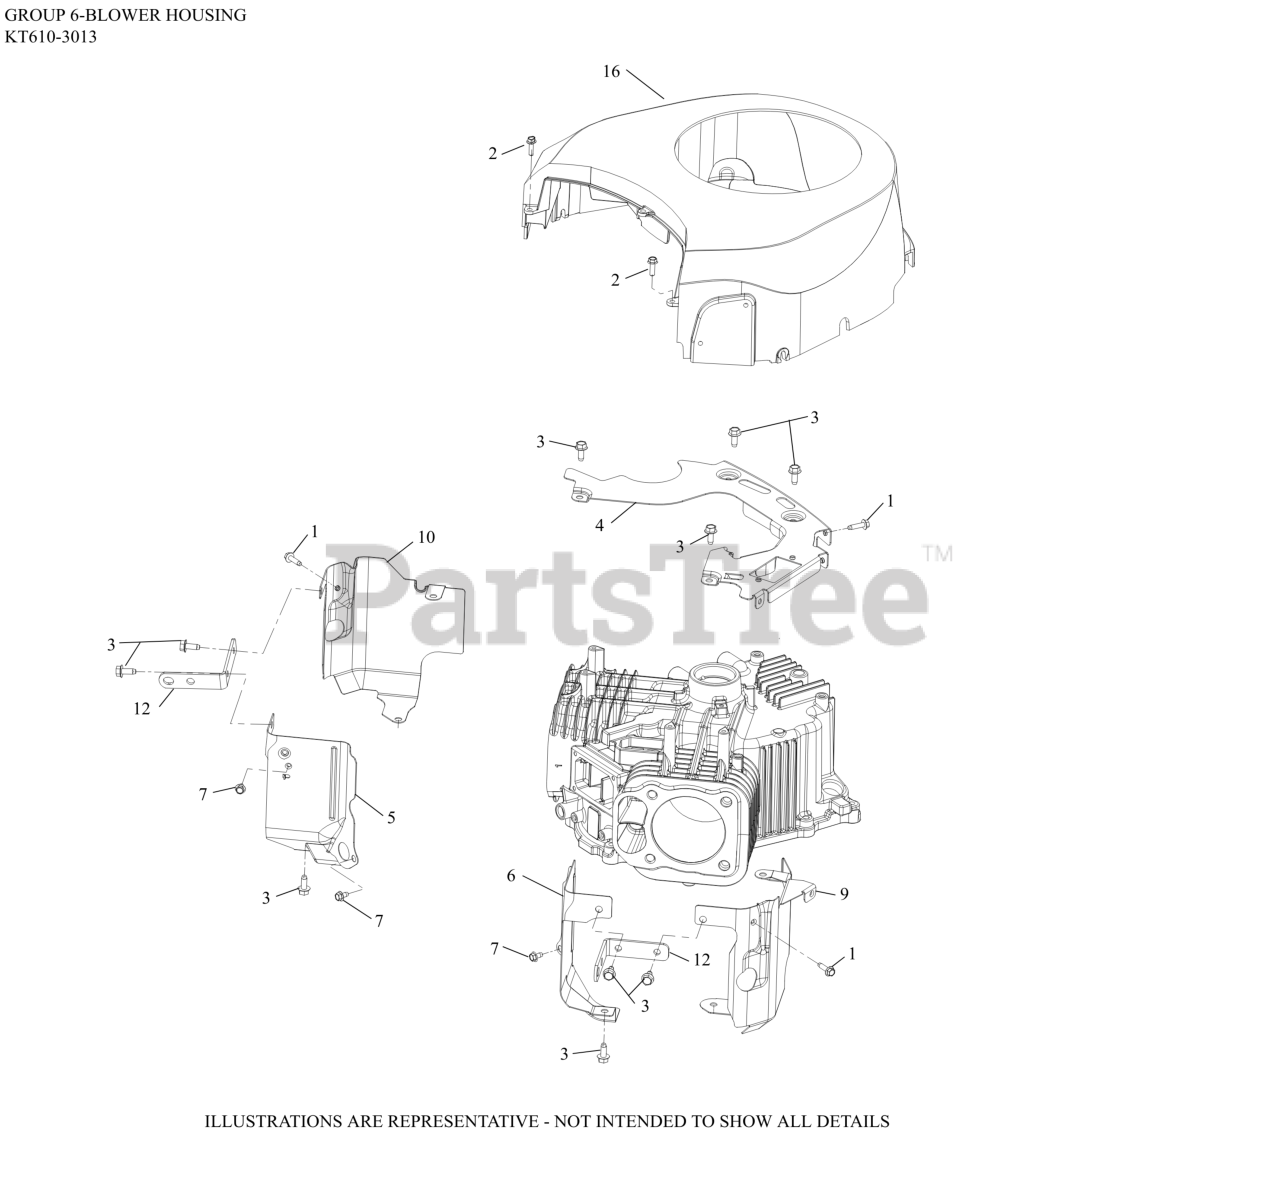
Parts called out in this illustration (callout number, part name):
1	SCREW, THD FRM-USE 25 086 473-S
2	SCREW, HI-LOW
3	SCREW, THREAD FORMING
4	PLATE, BACKING
5	BAFFLE, VALLEY #1
6	BAFFLE, VALLEY #2
7	SCREW, THREAD FORMING
9	BAFFLE, LEFT BARREL
10	BAFFLE, RIGHT BARREL
12	STRAP, LIFTING
16	KIT, BLOWER HOUSING
